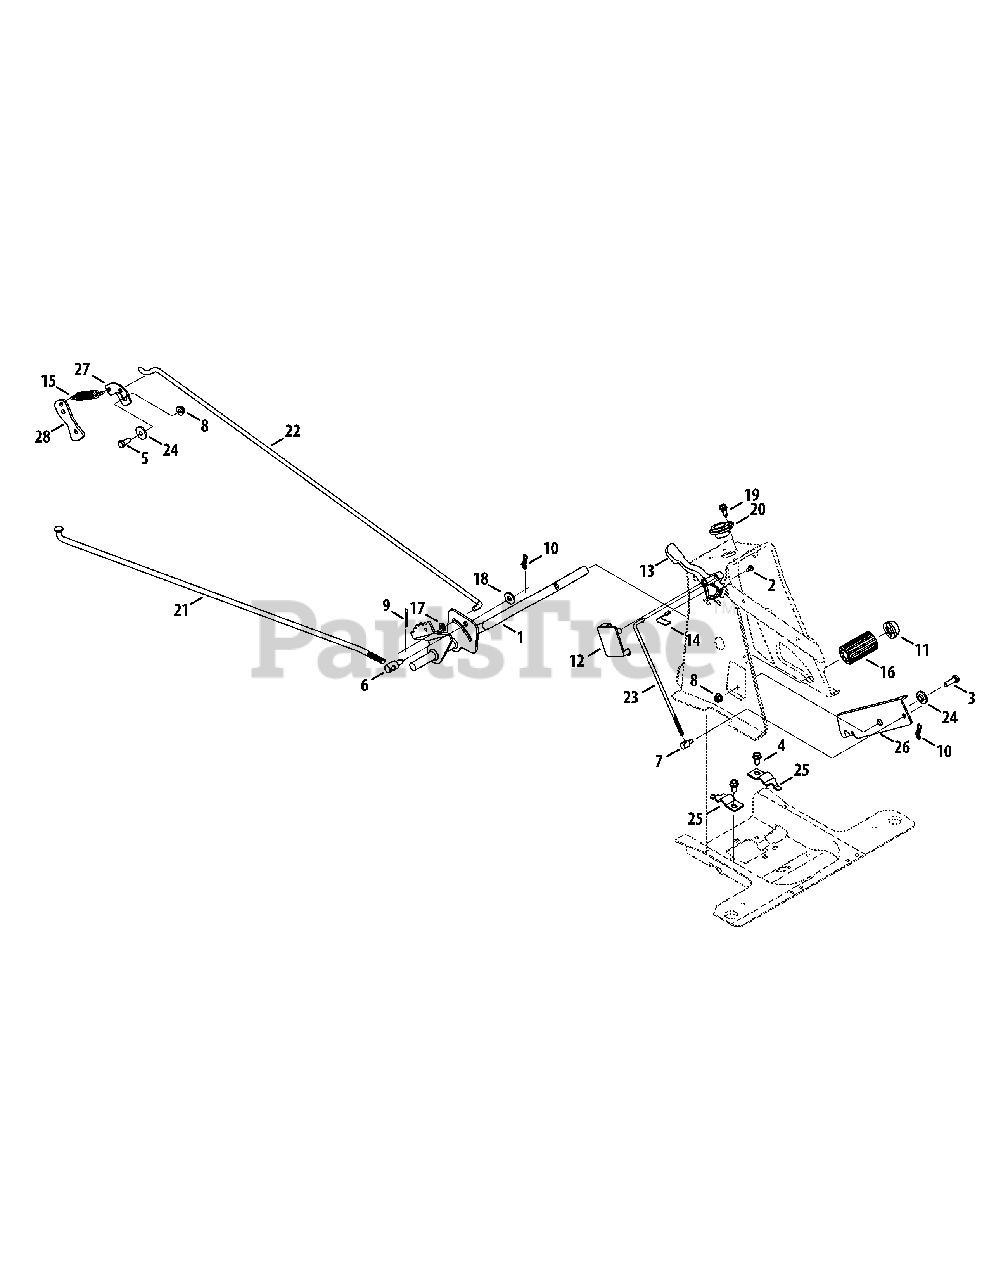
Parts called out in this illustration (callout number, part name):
1	Brake Pedal Assembly
2	Screw, #10-16:0.500
3	Hex Head Scerw, 5/16-18:1.00
4	Tap Screw, 5/16-18:.750
5	Hex Head Screw, 5/16-18:.75
6	Ferrule 3/8-24 X .375 Dia.
7	Adjustable Ferrule, 1/4-20 X 1.00
8	Flange Lock Nut, 5/16-18
9	Cotter Pin, 3/32X1.0
10	Bow-Tie Cotter Pin, 72
11	Push Cap, 5/8
12	Speed Control Cover
13	Speed Lever, 6-SPEED
14	Shift Spring
15	Extension Spring, .59 OD X 4.00 LG
16	Foot Pad, 2.5" LG.
17	Flat Washer, .330x.630x.064
18	Flat Washer, .380X.930X.110
19	Shoulder Screw, .368 X.113, 1/4-20
20	Steering Col. Bearing, .880 ID X 1.36
21	Variable Speed Control Rod
22	Brake Rod
23	Speed Selector Control Rod
24	Shoulder Spacer
25	Pedal Strap Support Bracket, 5/8
26	Speed Latch Bracket
27	Brake Cam Bracket
28	Brake lever Bracket
